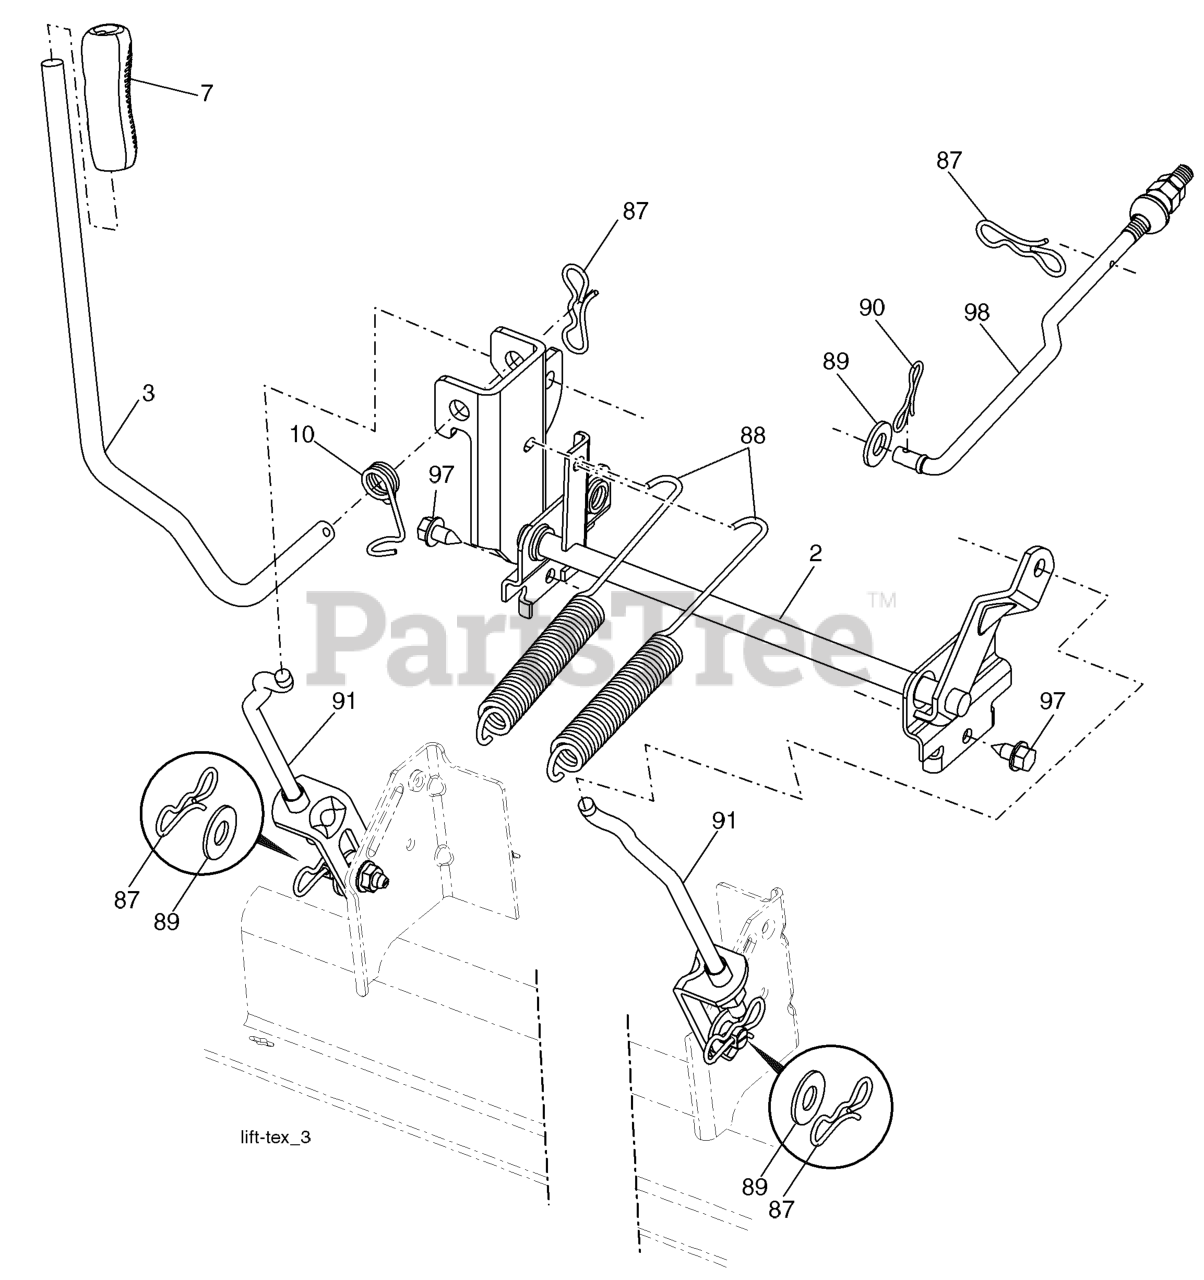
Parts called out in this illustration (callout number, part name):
2	SHAFT.ASM.LIFT.CROSS.H
3	LEVER.LIFT.HANDLE.GT
10	SPRING.TORSION.LIFT.HANDLE
87	PIN.COTTER.7/16.BOW TI.
88	SPRING.LIFT.ASSIST.GT2
89	WASHER.CLEAR.ZINC
90	PIN.COTTER.5/16.BOW TI
91	LINK.ASM.LIFT.54"TG
97	SCREW, 3/8-16X3/4
98	LINK.ASM.SUSP.FRONT.MWR.10.5
